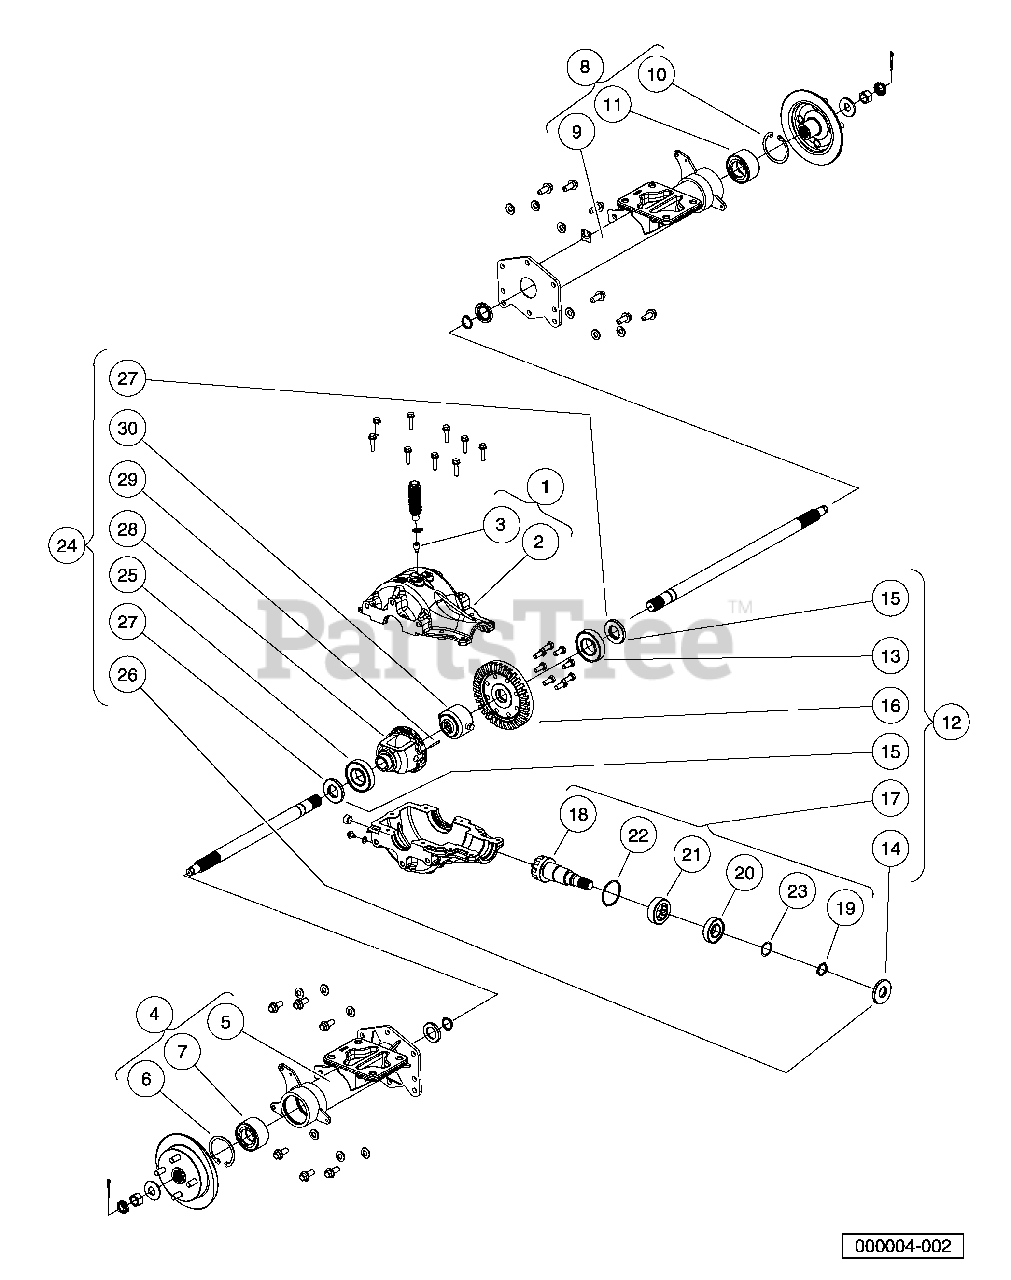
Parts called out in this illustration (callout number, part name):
1	Asm, Gearcase, Upper
2	Gearcase, Upper, Machined
3	Vent, Top, Upper Housing
4	Asm, Axle Tube, RH
5	Weldment, Axle Tube Rh
6	Ring, Retaining, Internal
8	Asm, Axle Tube, LH
9	Weldment, Axle Tube Lh
10	Ring, Retaining, Internal
12	Kit, Rear Axle Gear Repair
13	Bearing, Ball
14	Seal, Dual-Lip 25x 62x 7tc
15	Seal, Dual-Lip 30x 62x 8tc
17	Asm, Pinion W/ Bearings
18	Pinion, I0t Machined
19	Ring, Retaining, External
20	Bearing, Ball.
21	Bearing, Needle, Drawn Shell
22	Washer, 2.625 X 2.367 X .06
23	Shim, 1.50 X 1.189 X .008
24	Asm, Differential & Carrier
25	Bearing, Ball
26	Seal, Dual-Lip 25x 62x 7tc
27	Seal, Dual-Lip 30x 62x 8tc
28	Housing, Differential, Mach
29	Pin, Dowel, 4 X 35
30	Asm, Locker, Nongrease/Spacers
